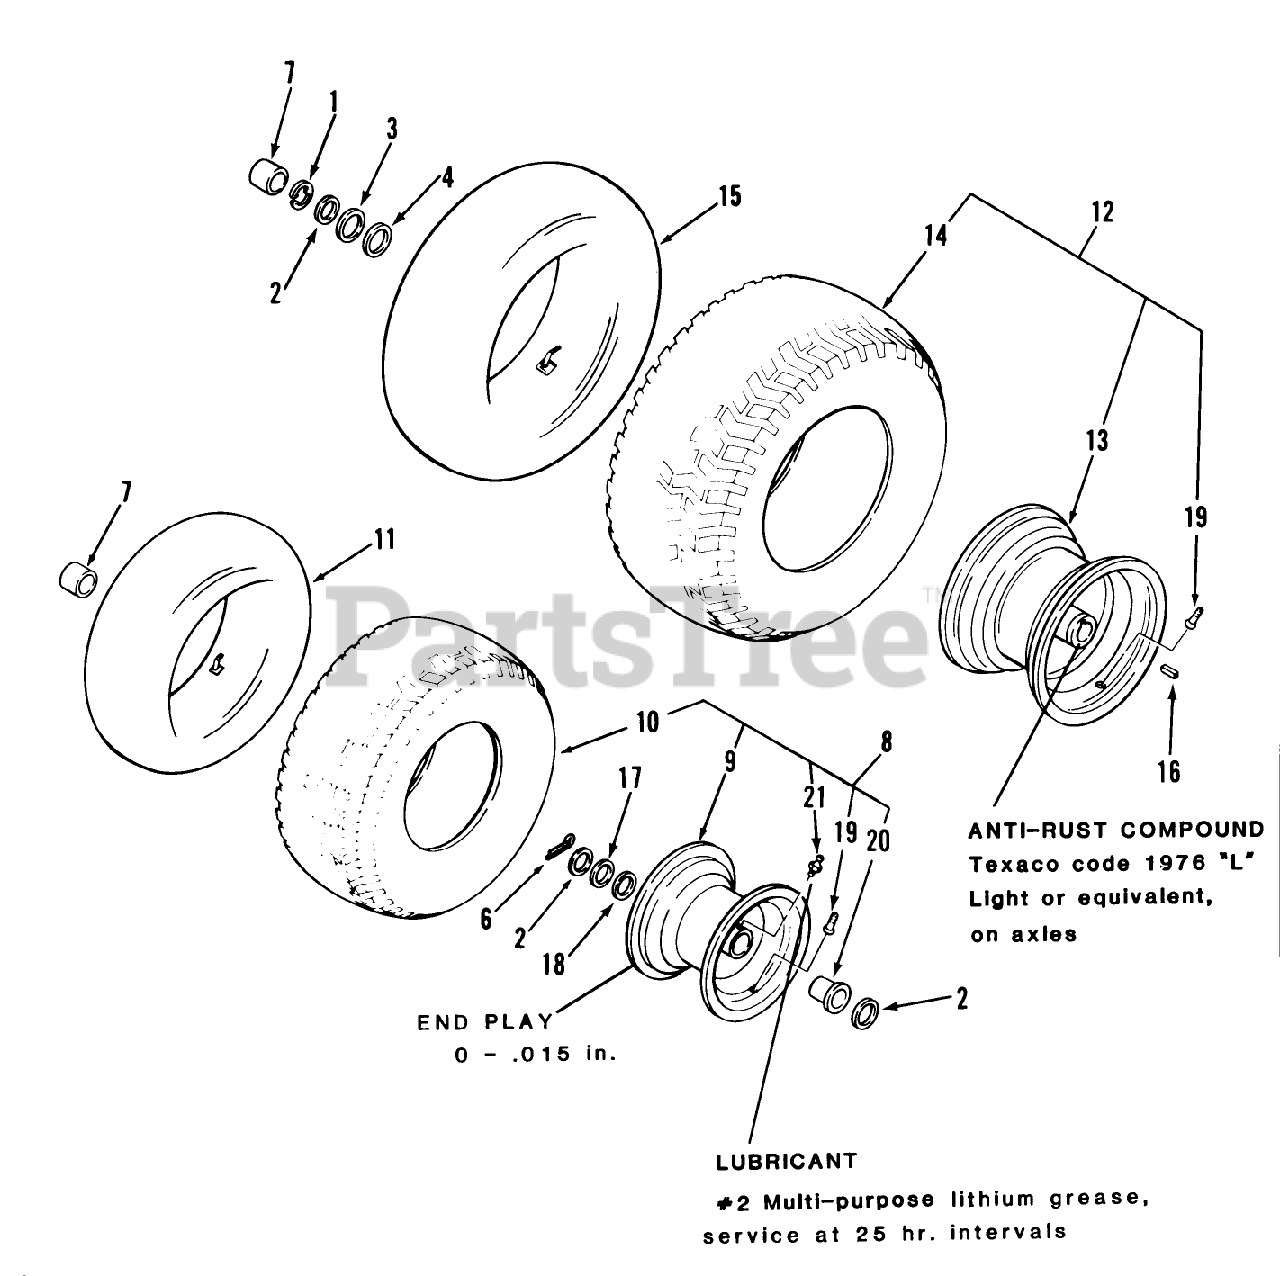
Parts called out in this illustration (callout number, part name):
2	WASHER-FLAT
3	WASHER-SHIM
4	WASHER
6	COTTER PIN-4
9	Front Wheel 5-Speed Only
13	WHEEL ASSY
16	SQ KEY
17	WASHER
18	WASHER-SHIM
19	VALVE
20	BUSHING-FLANGED
21	ZERK-GREASE
